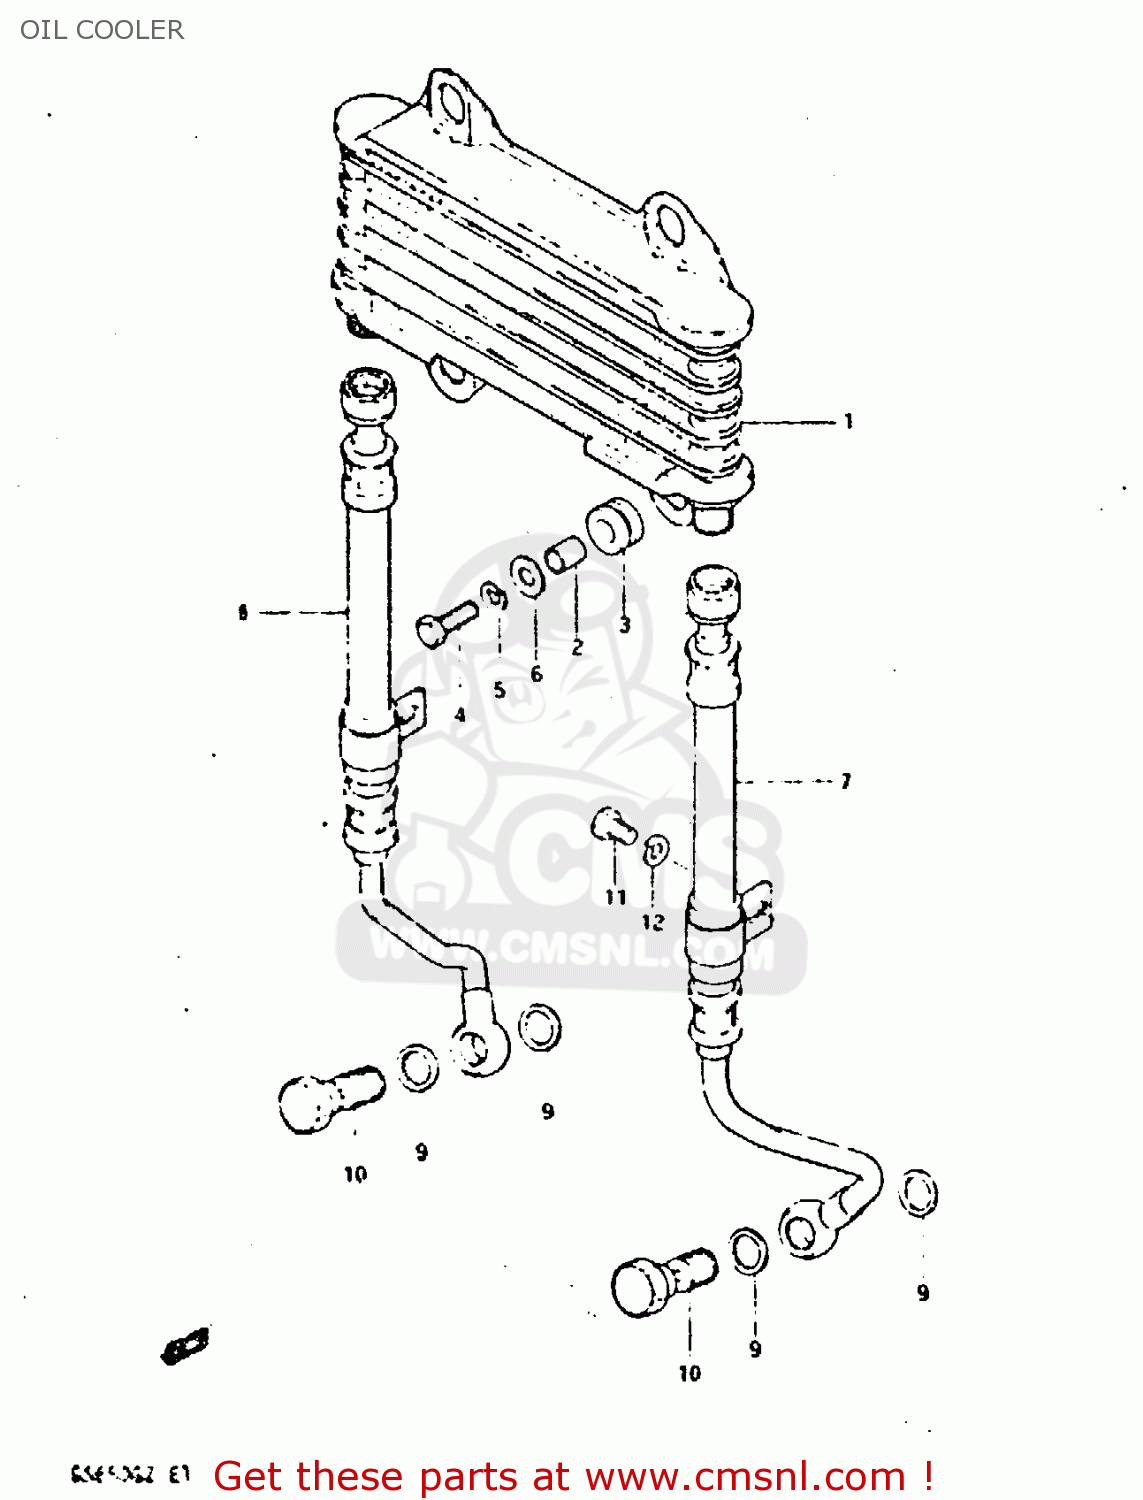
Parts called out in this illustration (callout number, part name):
1	COOLER ASSEMBLY,ENGINE OIL
2	SPACER (6.8X10X10)
3	CUSHION
4	BOLT
5	LOCK WASHER
6	WASHER
7	HOSE, OIL LH
8	HOSE, OIL RH
9	GASKET(14X19.2X2) (NAS)
10	BOLT UNION
11	BOLT
12	LOCK WASHER
